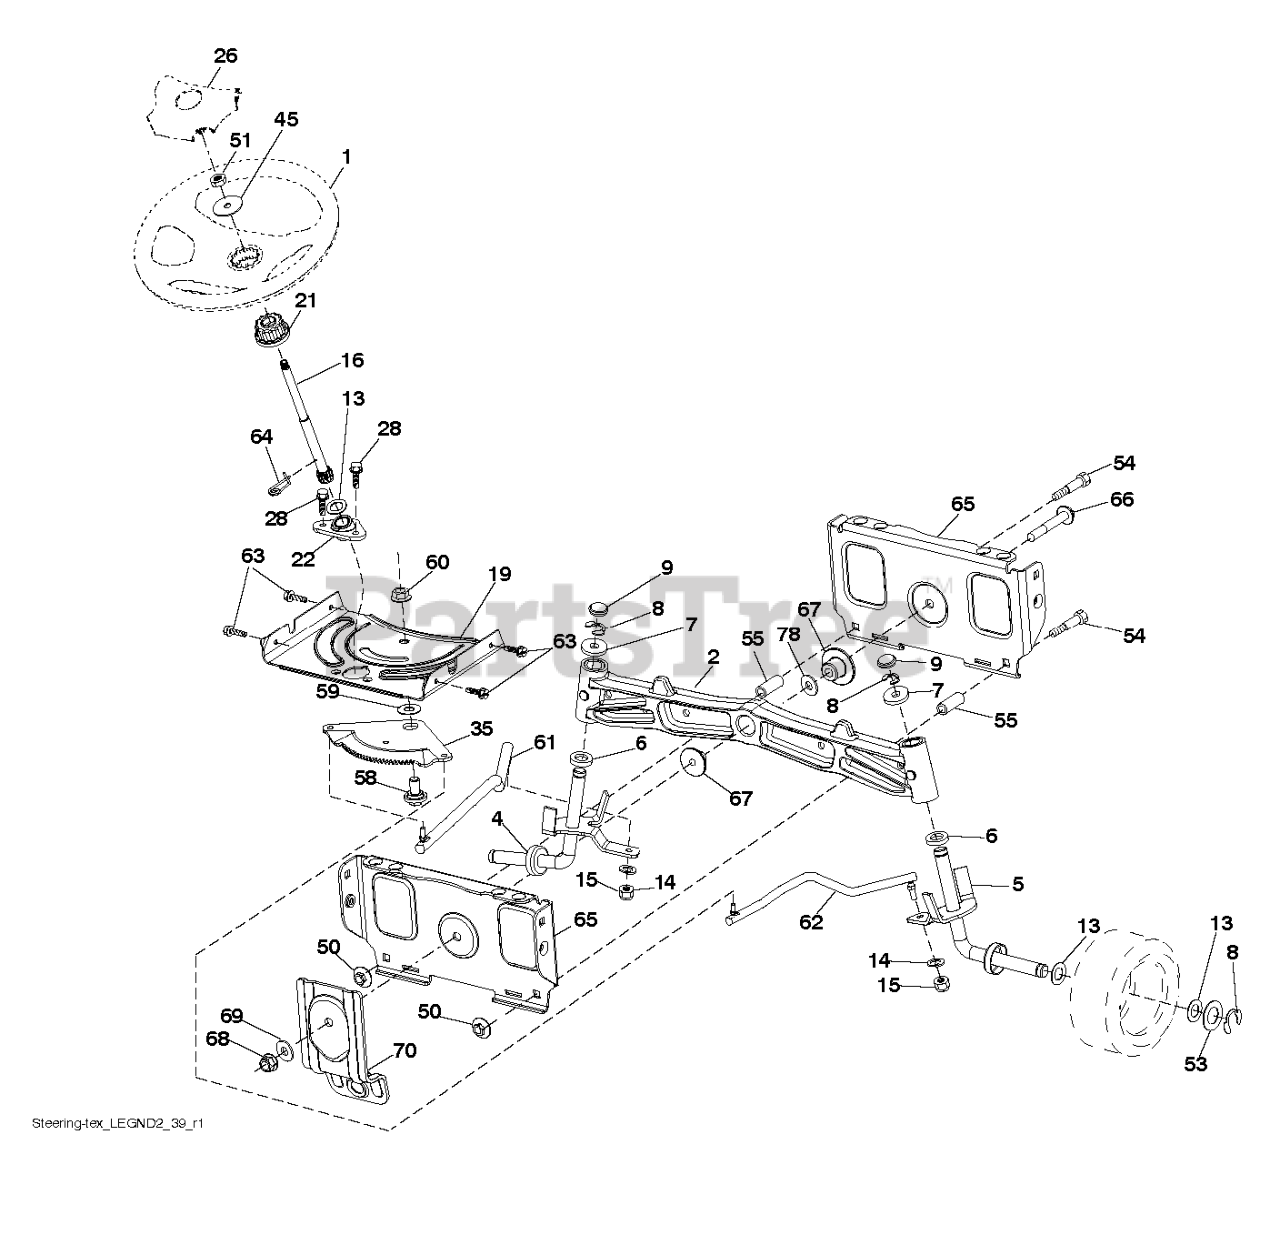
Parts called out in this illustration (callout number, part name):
1	RP WHEEL.STEER.HUSQ.PREM.OVMLD
2	AXLE.CAST.IRON
4	SPINDLE.WELDED.LH.16"TEX
5	SPINDLE.WELDED.RH.16"TEX
6	THRUST WASHER
9	CAP.SPINDLE.BLACK
14	WASHER, LOCK 3/8
15	NUT CROWNLOCK 3/8-24
16	SHAFT, STEERING
19	PLATE.STEER.DDL.NLT/NG
21	ADAPTER, WHEEL STNG..
22	STEERING.SUPT.LOWER.
26	RP INSERT.CAP.WHL.STRG.HUSQ.
28	SCREW, 3/8-16X3/4
35	GEAR.SECTOR.PLATE.DDL.
45	WASHER 9/16"ID, 2 3/8"OD
50	NUT LOCK FLG 3/8-16 UNC
51	NUT.HEX.1/2-20
53	WASHER.HARDENED
55	SPACER.BRACE.AXLE
58	BOLT.SHOULDER.SECTOR.P
59	WASHER.THURST.SECTOR.S
60	NUT FLANGE LOCK 5/8-11
61	DRAGLINK.LH.BALLSTUD.D
62	DRAGLINK.RH.BALLSTUD.D
63	SCREW
64	RETAINER.CLIP.SPRING.S
65	BRACE.AXLE.FRONT.NLT/N
66	BOLT HEX FGHD 7/16-14 X 3 SERR
67	BUSHING.PM.FRONT AXLE
68	NUT.LOCK.FLANGE.7/16
69	WASHER.1.5X.505X.118
70	BRKT.DECK.SUSPENSION.F
78	THRUST WASHER
